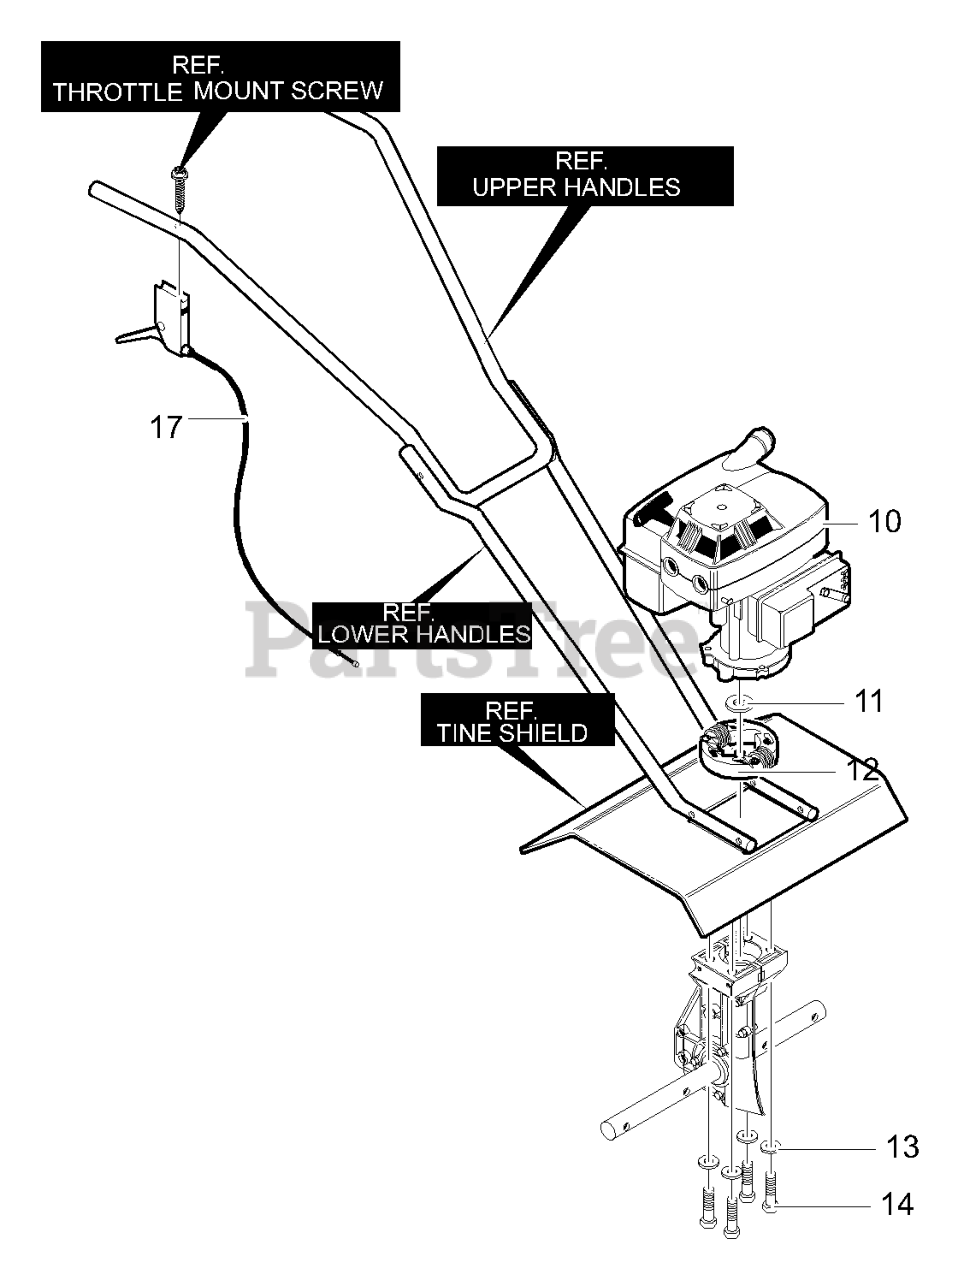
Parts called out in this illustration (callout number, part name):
11	Flat washer
13	Washer, Regsptlk
14	Screw
17	Cable, Throttle
